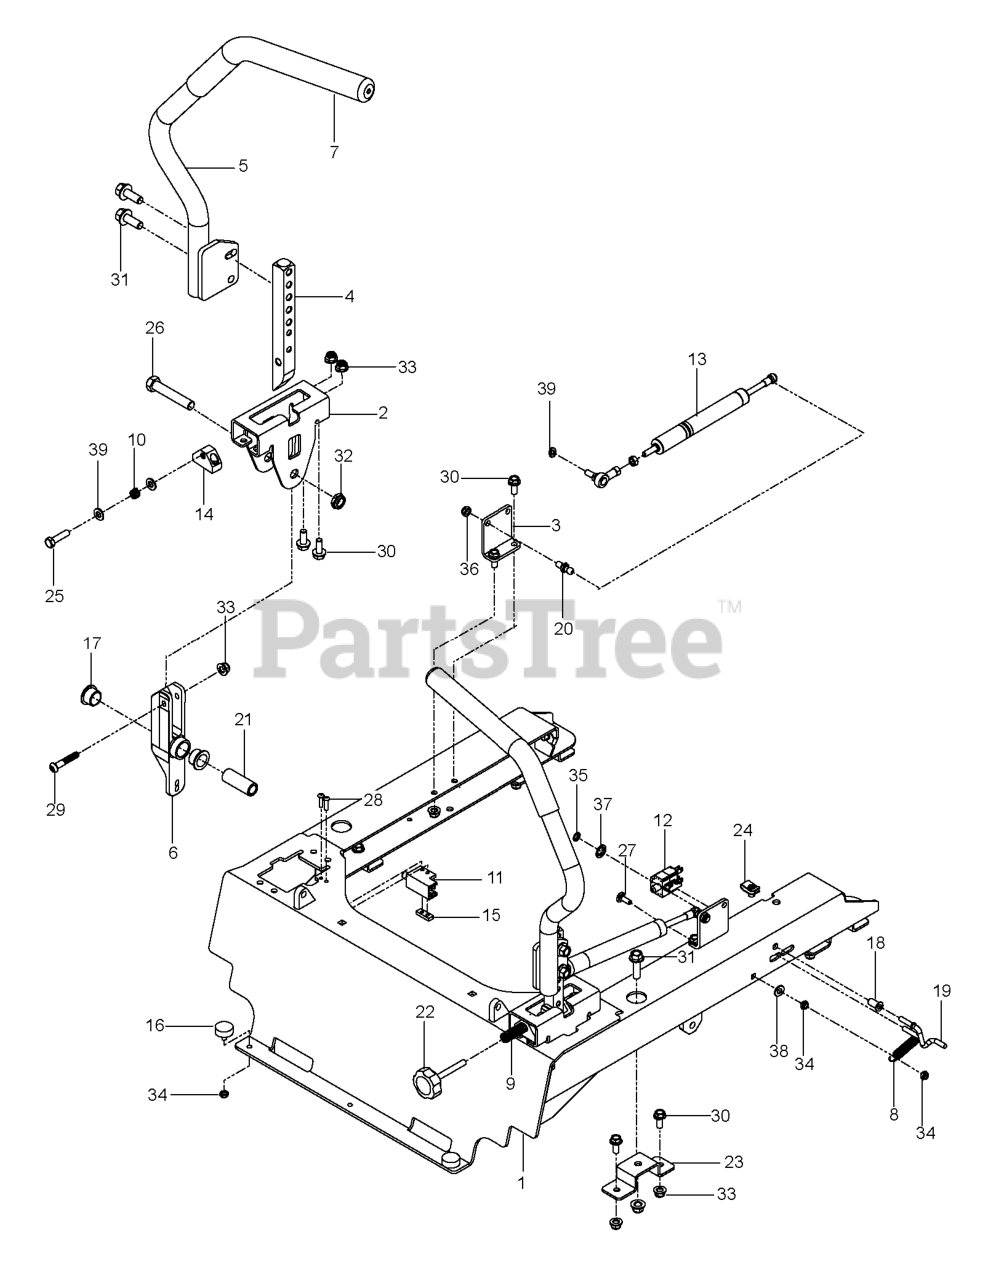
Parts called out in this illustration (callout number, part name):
1	FRAME SEAT MOUNT ORANGE
2	BRACKET.CONTROL.NARROWSLOT.BLK
3	BRACKET.DAMPENER
4	LEVER, MOTION
5	LEVER.WITH GRIP.RT
6	LEVER.CONTROL.SHORT
7	GRIP - DRIVE LEVER 12"
8	SPRING, EXTENSION
9	SPRING COMPRESSION 2.0
11	SWITCH INTERLOCKT
12	SWITCH, BRAKE 3P
13	ASSEMBLY, DAMPENER
14	BLOCK TRACKING CONTROL ZTR
15	BLOCK, LOWER
16	BUMPER, 1/4-20 STUD, 1/4
17	BEARING, FLANGE
18	BUSHING, 1/4 FLANGE
19	LINK, SWITCH
20	STUD.BALL.10MM
21	SPACER, PIVOT CONTROL
23	MOUNT, MID-SECTION, BLK
24	U-CLIP 5/16-18 NUT RETAINER
25	BOLT.5/16-18X1-1/4 FULL.THREAD
26	HCS 1/2-13 X 2-3/4 GD 5 ZD
27	BOLT
28	SCR #10-24 X .75 SKT HD BLK
29	SCREW 5/16-18 X 1 3/4 BTN-HD
30	HHFS 5/16-18 X 3/4
31	HHFS 3/8-16 X 1 GRD 5 ZD
32	NUT 1/2-13 HEX JM NYL
33	5/16-18 NYLOC FLANGE NUT
34	JAM NUT 1/4C (2 2 PW01)
36	NUT.71038.31-18.HEX.NYLOCK
37	NUT 3/8 PALNUT RTNG BLK PHOS
38	WASHER
39	WASH.5/16.SLW.ZD
